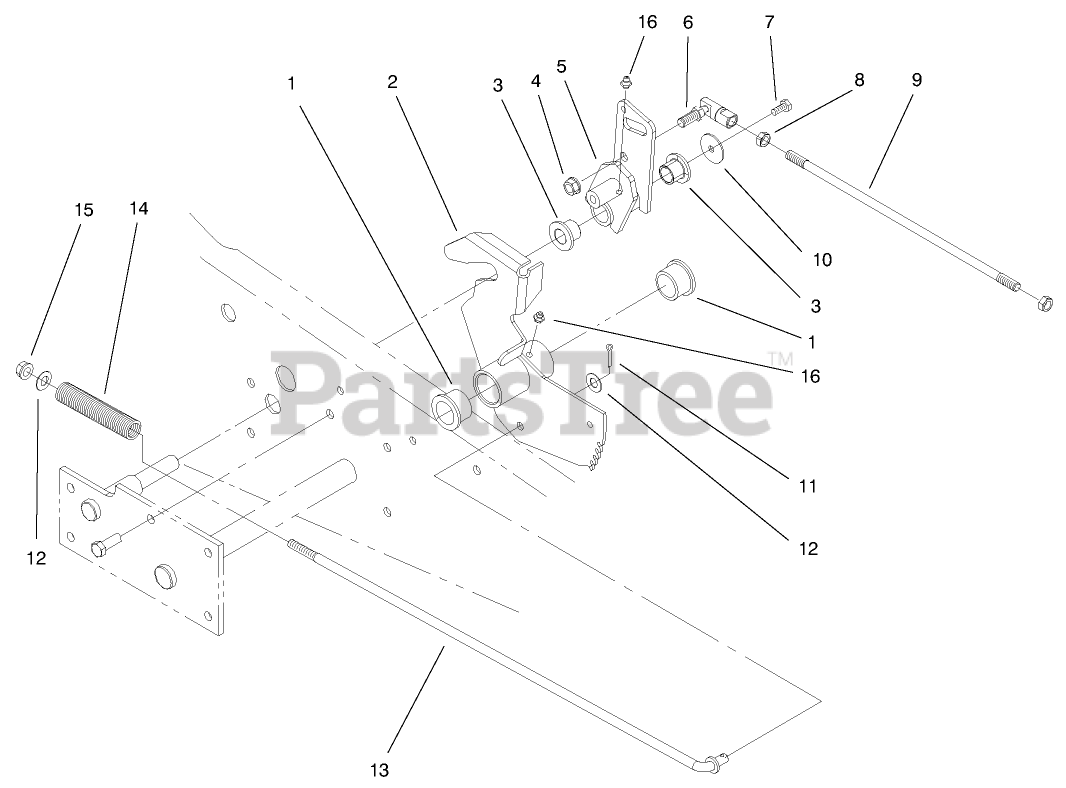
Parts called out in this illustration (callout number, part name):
1	BUSHING-FLANGED
2	PLATE-PIVOT, BRAKE
3	BUSHING
4	NUT-LOCK
5	PIVOT-HYDRO
6	END-TIE ROD, LH
7	SCREW-HH
8	NUT-HEX JAM, LH
9	ROD-PIVOT TO PEDAL
10	WASHER-FLAT
11	PIN-COTTER
12	WASHER-FLAT
13	ROD-BRAKE
14	SPRING-COMPRESSION
15	NUT-LOCK, NI
16	FITTING-GREASE
